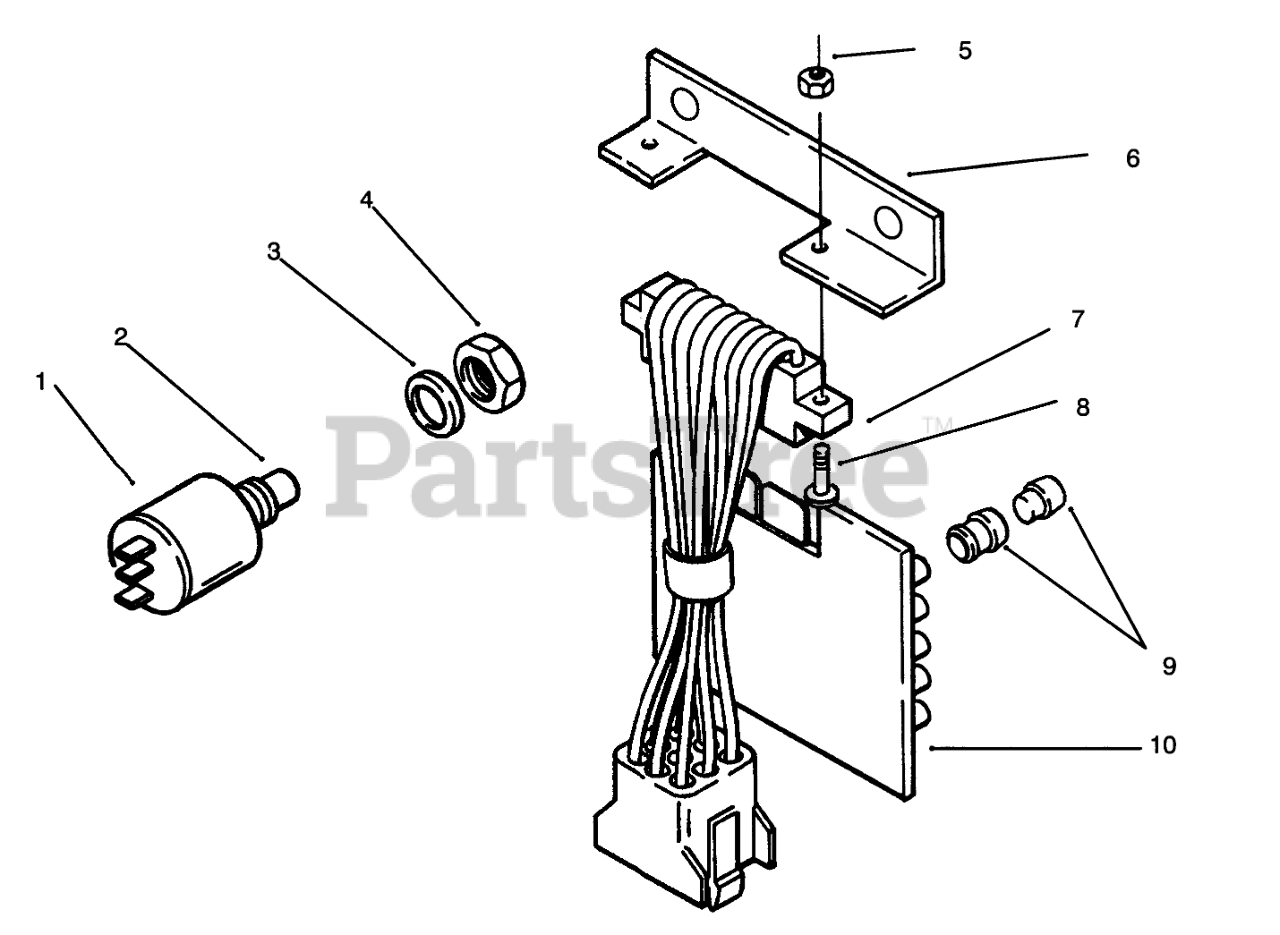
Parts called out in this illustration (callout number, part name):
1	Test Switch (Incl. Ref. #2-4)
2	BUTTON F/W 116796
3	Washer
4	NUT F/W 116796
4	Boot
5	NUT-HEX
6	BRACKET
7	P.C. BOARD HARNESS
8	Screw
9	ASSY LENS & BUSHING
10	Board-Pc
